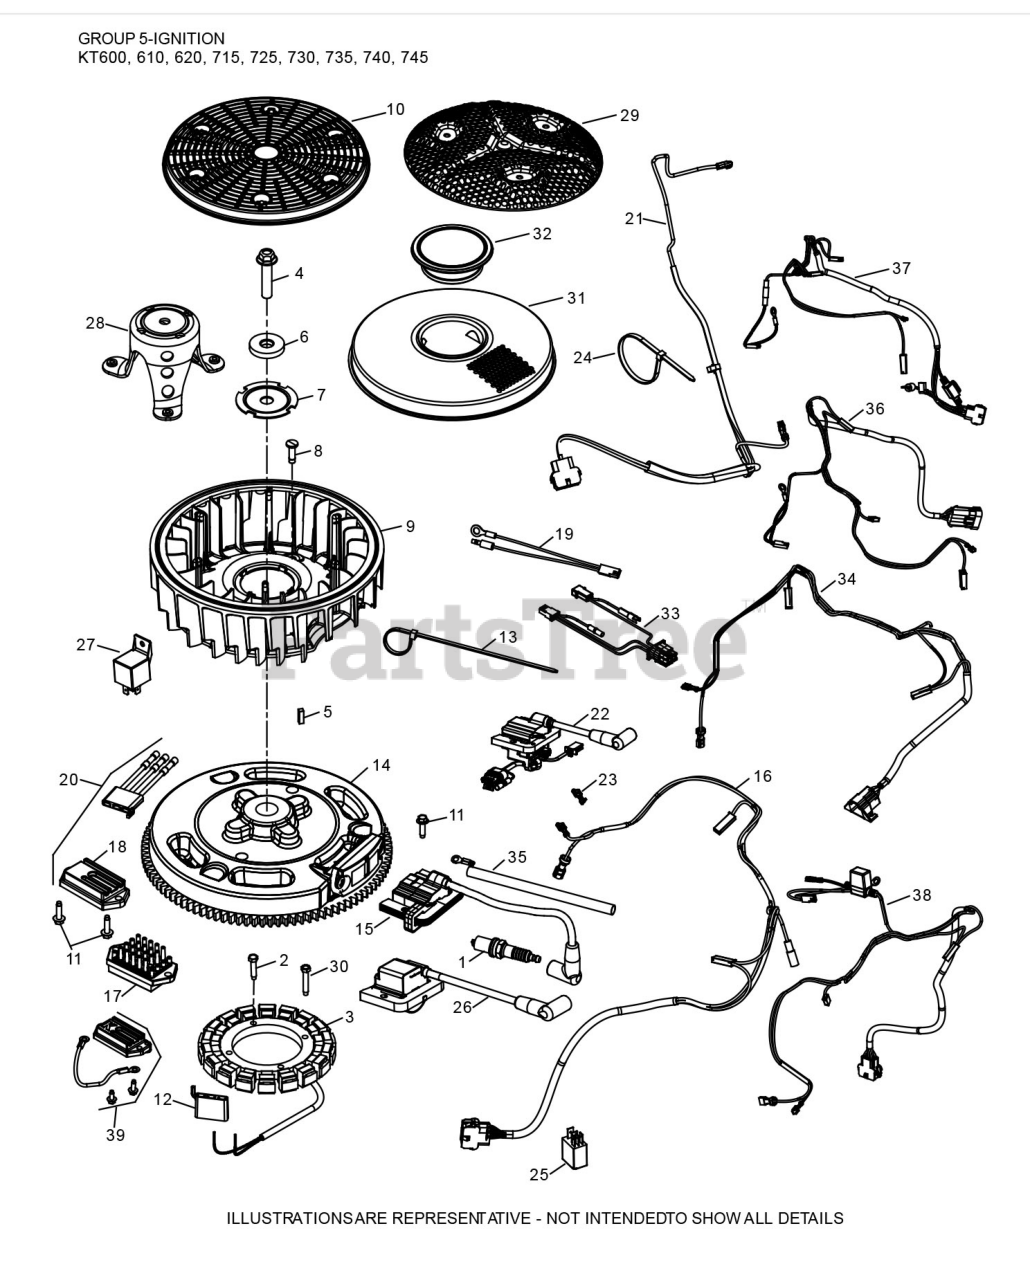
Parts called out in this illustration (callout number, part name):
1	SPARK PLUG RFI
2	THREAD FORMING SCREW
3	KIT-STATOR
4	HEX FLANGE BOLT
7	PLATE-FAN MOUNTING
11	THREAD FORMING SCREW
14	FLYWHEEL ASSEMBLY
15	MODULE-IGNITION C
16	WIRING HARNESS W/FUEL SHUTDOWN
18	REGULATOR RECTIFER 12/15A HALFWAVE
